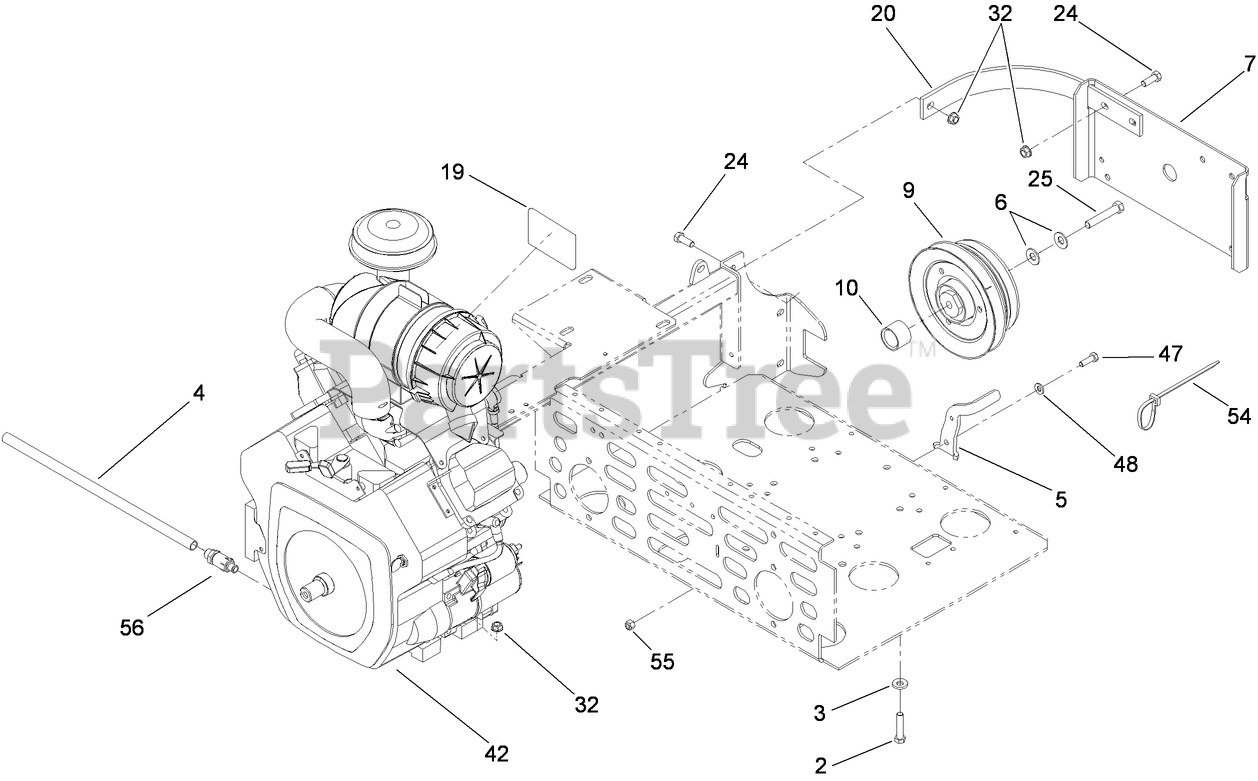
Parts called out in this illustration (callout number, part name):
2	SCREW-HH
3	WASHER-BELLEVILLE
4	TUBE-DRAIN, OIL
5	ANCHOR-CLUTCH
6	WASHER-SPRING
7	GUARD-CLUTCH
9	CLUTCH
10	SPACER-CLUTCH
20	STRAP-GUARD
24	SCREW-HH
25	SCREW-HH
32	NUT-HHF, WHIZ
47	SCREW-HH
48	WASHER-SPRING
54	TIE-PLASTIC
55	NUT-LOCK, NI
56	VALVE-DRAIN, OIL
